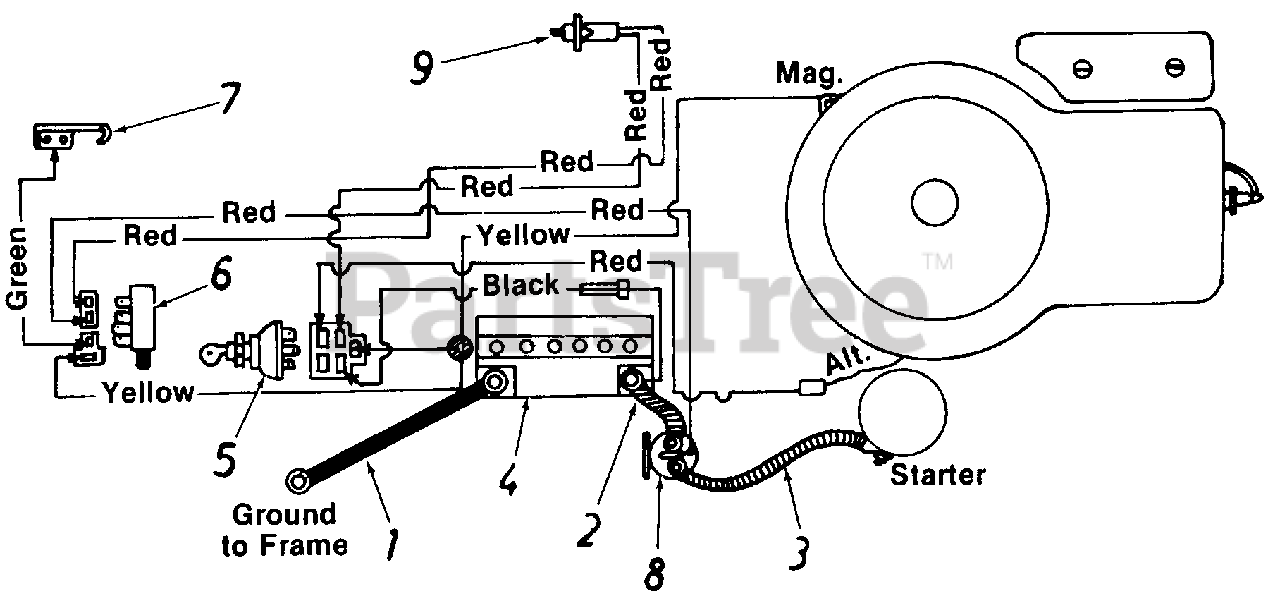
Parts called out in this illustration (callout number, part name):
1	Ground Wire-11.5" Lg.
2	Electric Wire 11.5" Lg. (Red)
3	Electric Wire-7.25" Lg.
4	Battery
5	Ignition Switch
6	Safety Switch
7	Spring Switch
8	Solenoid
9	Safety Switch
